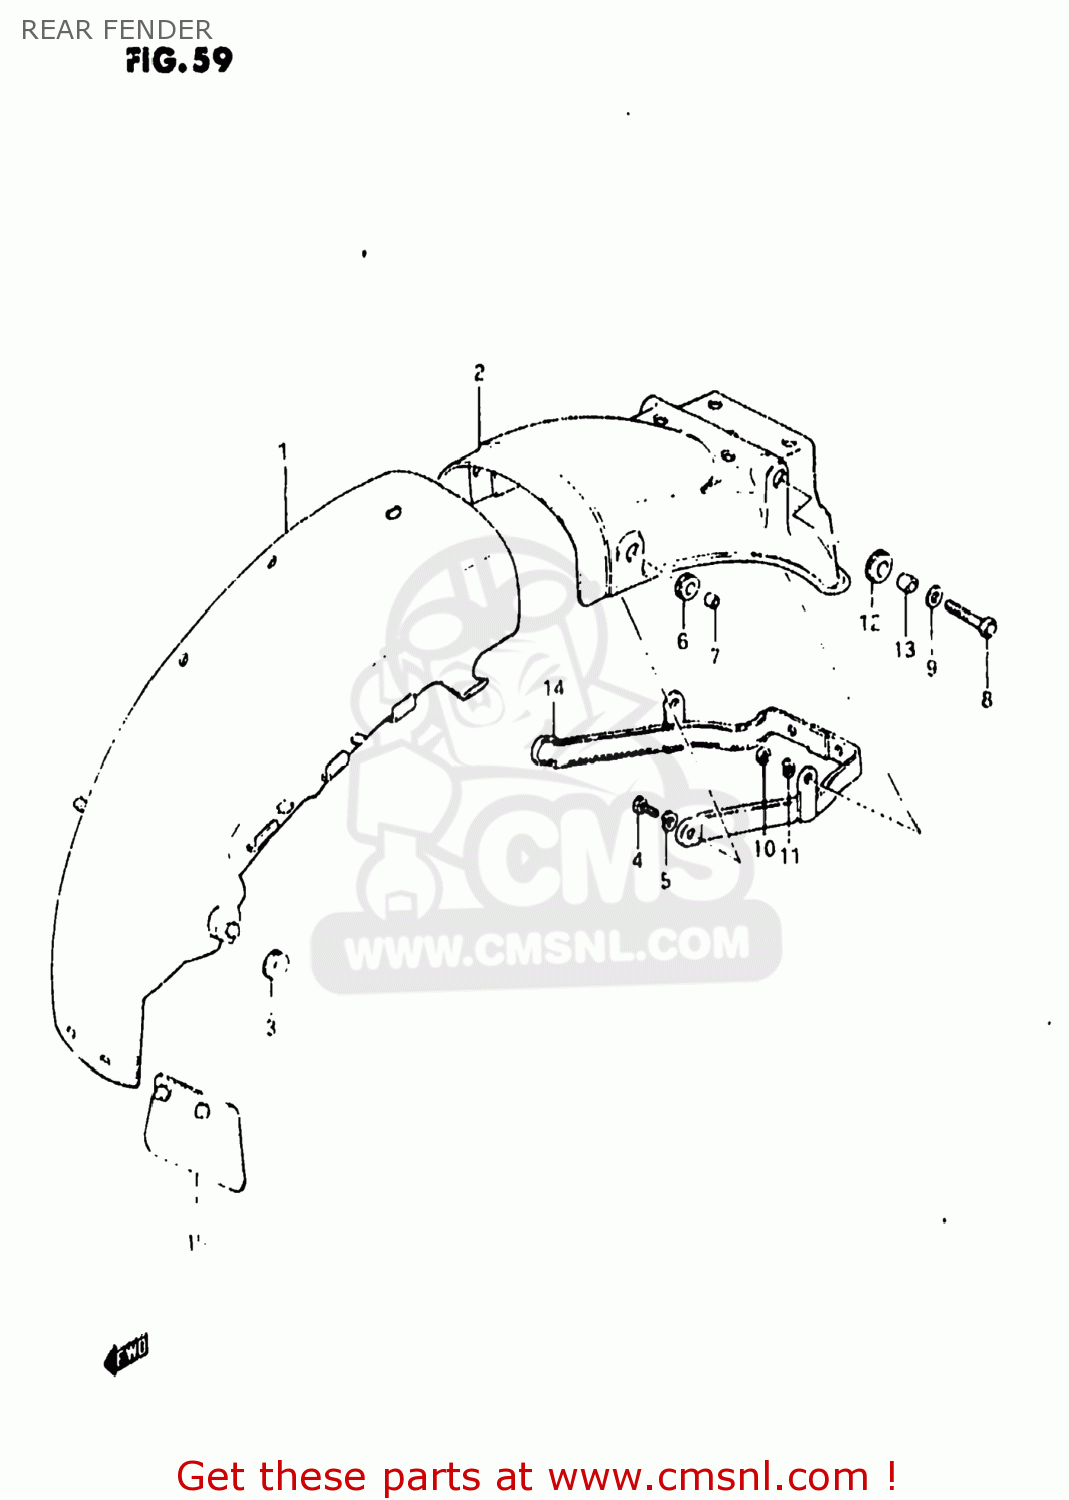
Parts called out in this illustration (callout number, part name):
1	FENDER,REAR
2	FENDER,REAR
3	CUSHION
4	BOLT, UPPER
5	LOCK WASHER
6	CUSHION
7	SPACER(6.1X9X7.5)
8	BOLT (8X30)
9	WASHER
10	NUT
11	LOCK WASHER
12	CUSHION
13	SPACER (8.2X12X7.5)
14	REINFORCEMENT,REAR FENDER
15	GUIDE,RR FENDER MUD
